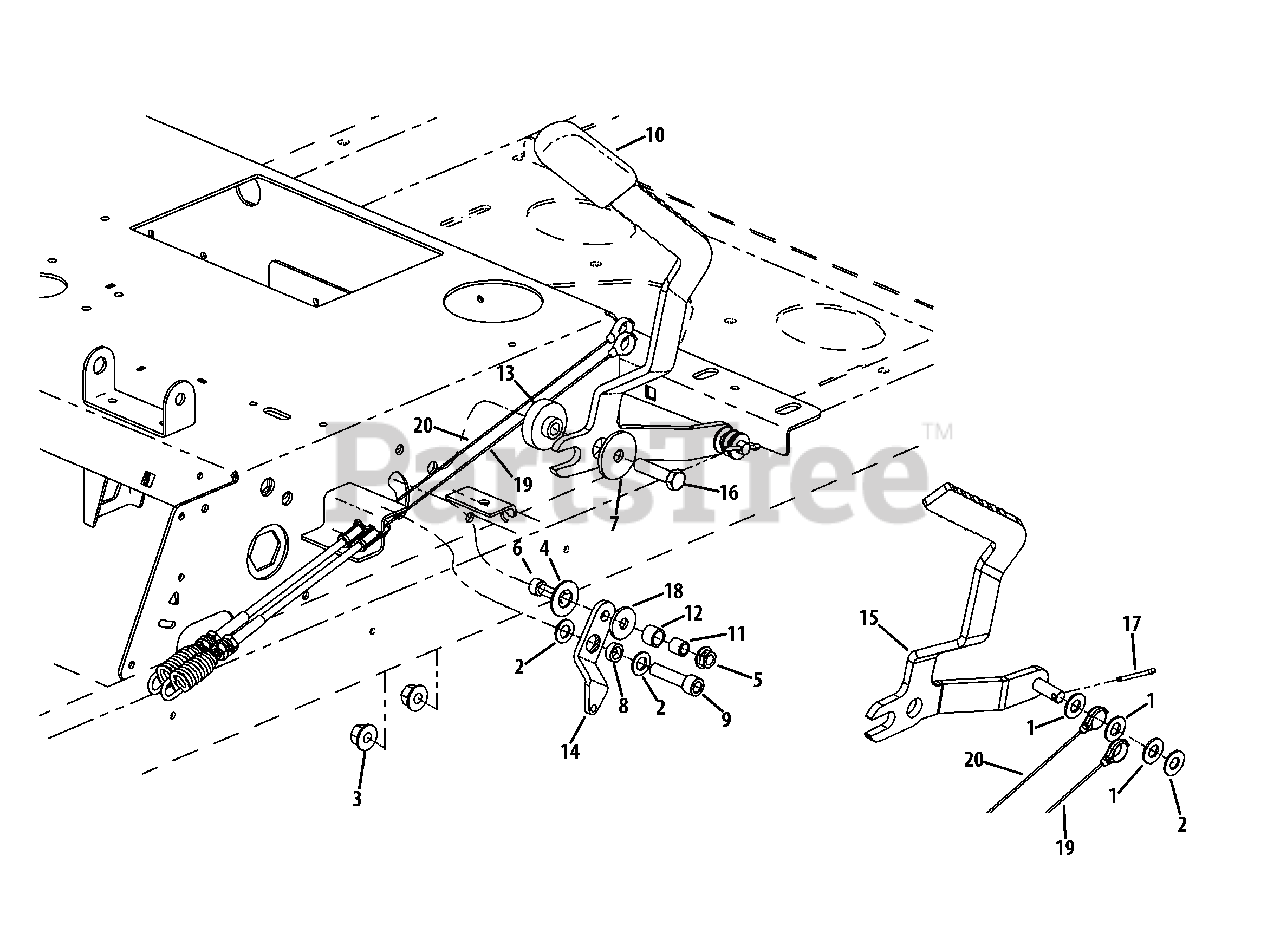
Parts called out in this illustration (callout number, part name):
1	Flat Washer, .455 x 1.00
2	Flat Washer, .375 x .738 x .063
3	Counterlock Flange Nut, 3/8-16
4	Flat Washer, .570 x 1.12 x .062
5	Nut, 5/16-18, Centerlock
6	Sockethead Capscrew, 3/8-16 x 1.0
7	Flat Washer, .390 x 1.50 x .134
8	Spacer, .380 x .563 x .196
9	Sockethead Capscrew, 3/8-16 x 1.50
10	Parking Brake Grip
11	Spacer, .322 x .438 x .44
12	Spacer, .442 x .563 x .405
13	Step Hub, .379 x 1.5 x .257/.400
14	Lockout Lever Plate
15	Brake Handle
16	Hex Head Cap Screw, 3/8-16 x 1.50
17	Cotter Pin, 1/8 x .75
18	Washer, .345 x 1.00 x .100
19	Left Hand Brake Cable
20	Right Hand Brake Cable
